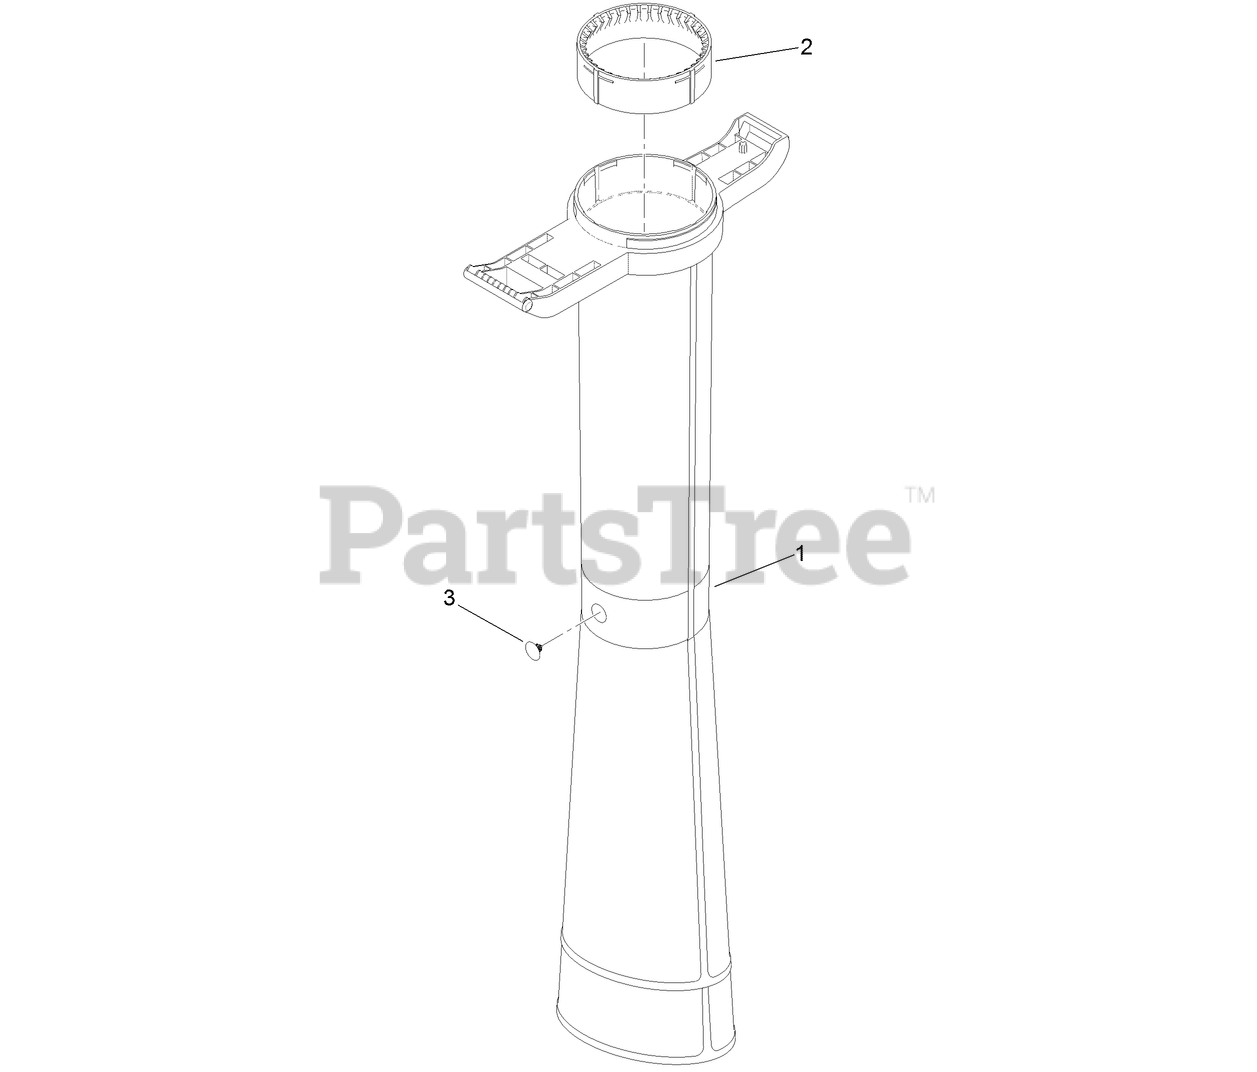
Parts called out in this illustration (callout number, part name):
1	VACUUM TUBE ASM
2	RING-SHRED
3	FASTENER-RATCHET
